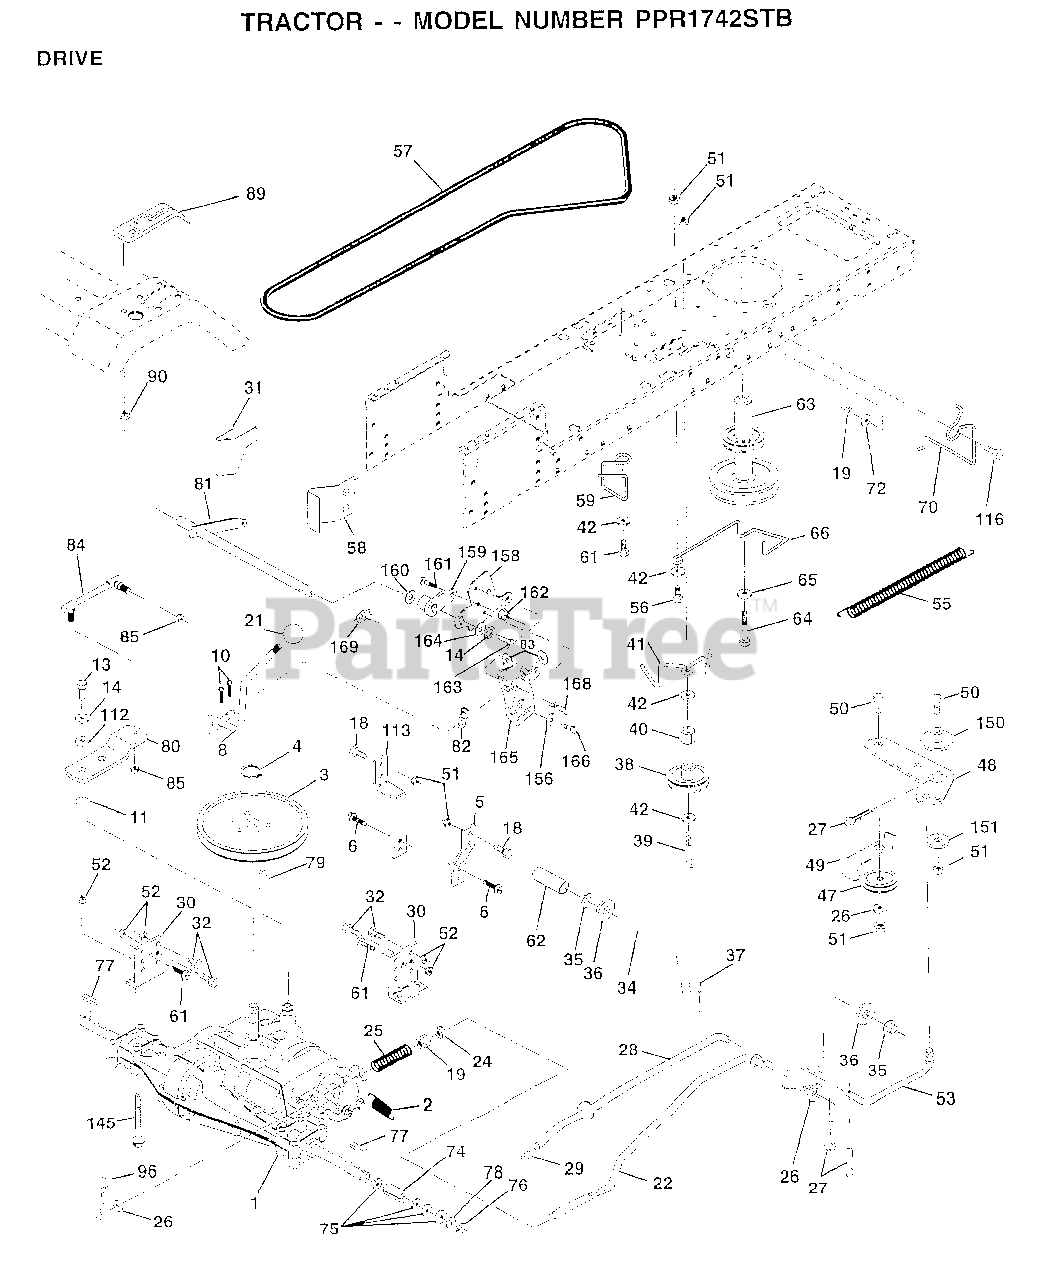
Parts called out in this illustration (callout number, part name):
2	SPRING.BRAKE.RETU
3	PULLEY TRANS
5	STRAP TORQUE
6	SCREW
8	ROD.SHIFT.FENDER.ADJ.LT.CRD
10	PIN COTTER 1/8
11	WASH-SHFT PLT LT
13	BOLT.1/4-28.W/PAT
14	LOCKWASHER
18	BOLT
19	NUT
21	KNOB DLX BLK/BLK
22	BRAKE ROD
24	NUT
25	SPRING ROD LT
26	WASHER
27	COTTER PIN
28	ROD.BRAKE.PARK.LT
29	PLUNGER CAP T
30	TRANSAXLE MTG BKT
31	"KEEPER,BELT LH T"
32	BOLT
34	SHAFT ASM-PEDAL F
35	NYLON BEARING
36	WASHER LT
38	FLAT IDLER PULLEY
39	BOLT
40	SPACER T
41	"KEEPER,BELT.IDLER FLAT"
42	WASHER
48	BELLCRANK.CLUTCH
49	RETAIN BELT
53	"LINK, CLUTCH T"
55	"SPRING, RETURN LT"
58	"KEEPER,BELT RH T"
59	KEEPER BELT CNTSP
61	SCREW
62	PEDAL COVER T
63	PULLEY.ENGINE
64	BOLT
65	LOCKWASHER
66	KEEPER-BELT
70	KEEPER BELT ENG
72	WASHER
74	SPACER AXLE
75	WASHER
76	E-RING LT
77	SQUARE KEY
78	WASHER
80	"ARM.SHIFT.20""TIRE"
81	SHAFT.ASM.CROSS
82	"SPRING,TORSION"
83	WASHER
84	LINK.TRANSAXLE.PMST/DANA
85	NUT.CNT.LOCK.1/4
89	CONSOLE.SHIFT.SLT
90	NUT
96	RETAINER M
112	WASHER LT
113	"STRAP,TORQUE"
116	BOLT RDHD 3/8-16
145	BOLT.HEX.FLGHD
150	BUSHING.BELLCRANK.GRD.DR
151	WASHER
156	WASHER.SRRTD.5/16
158	BRKT.SHIFT.MOUNT
159	HUB.SHIFT
160	WASHER
161	BOLT T
164	WASHER.5/8X.281X10GA
165	BRKT.PIVOT.LEVER
166	SCREW.5/16-18X5/8
168	BOLT.SHOULDER.5/16-18X.561
169	PLATE.FASTENING
